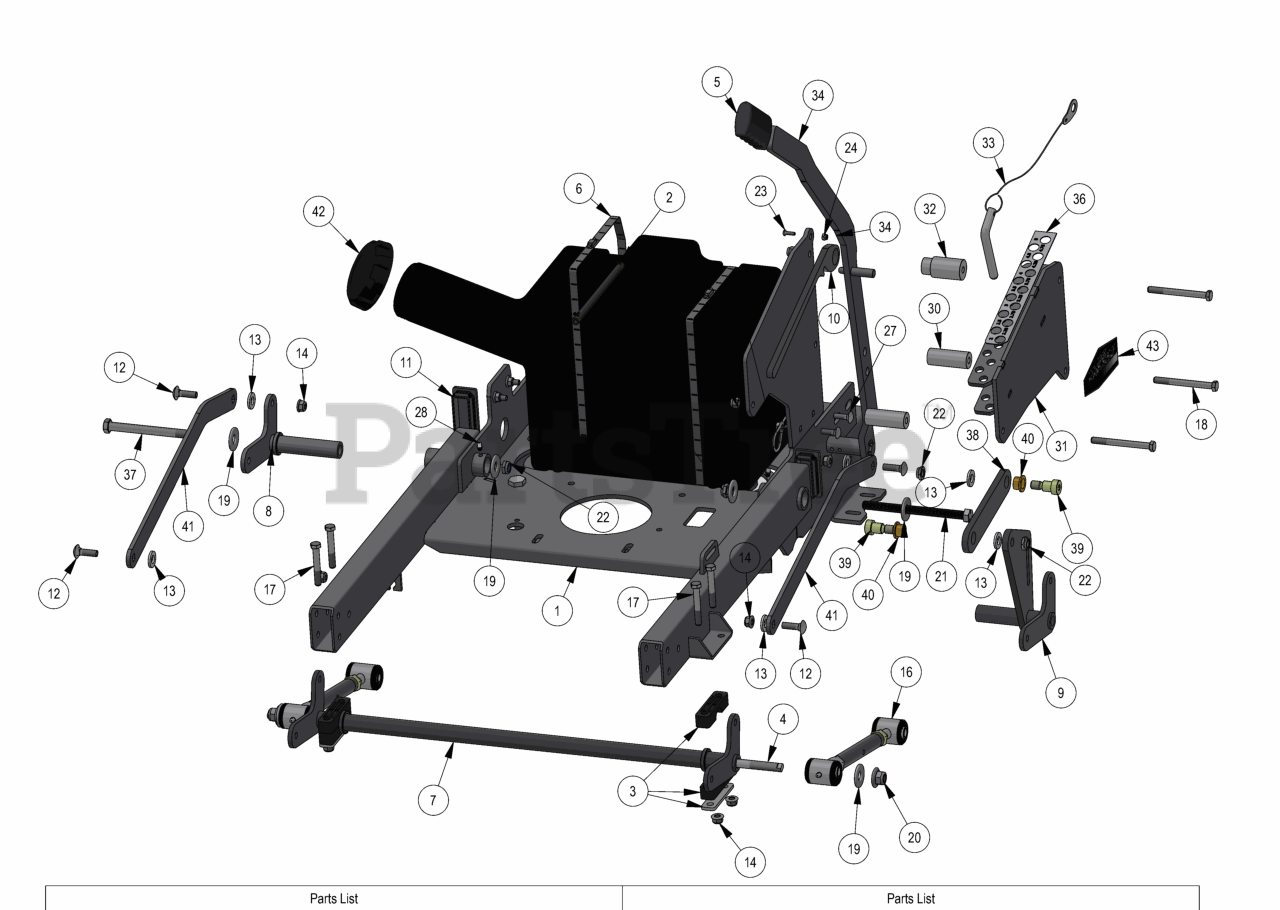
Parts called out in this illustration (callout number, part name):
1	2020 36" Stand On Frame
2	Revolt Fuel Line Assembly
3	Pillow Block Kit
4	2020 36 Stand On Turnbuckle Rod
5	2019 Stand On Lift Grip
6	2019 Stand On Gas Tank Strap
7	Revolt Front Actuator Bar Weldment 2020 36" Black
8	Revolt Rear Actuator Bar Weldment RH 2020 36" Black
9	Revolt Rear Actuator Bar Weldment LH 2020 36" Black
10	2019 Stand On Deck Lever Lock
11	1 1/2 x 3 Frame Plug
12	3/8-16 X 1-1/4 CARRIAGE BOLT ZINC
13	.505 ID X 1.000 OD X .125 THICK FLAT WASHER NYLON
14	3/8" Nylock Flange Nut
15	Revolt Cotter Pin for 7/8" to 1" shank
16	2018 Maverick Turnbuckle (Top Link)
17	3/8-16 X 2-1/2 HEX CAP SCREW (GR.5) ZINC
18	3/8-16 X 3-3/4 HEX CAP SCREW (GR.5) ZINC
19	1/2" Flat Washer
20	1/2-13 NYLON INSERT FLANGE LOCKNUT ZINC
21	1/2-13 x 6 1/2 Hex Bolt
22	1/2''-13 Jam Nut
23	10-24 X 5/8 BUTTON SOCKET CAP SCREW 18-8 STAINLESS STEEL
24	10-24 NYLON INSERT LOCKNUT ZINC
25	3/8 Nylock Nut
26	5/16" Nylock Flange Nut Zinc
27	5/16-18 X 1 CARRIAGE BOLT (GR.8) ZINC
28	1/4" Press in Grease Fitting
29	2023 Stand On Inner Adjustment Plate
30	Stand On Spacer 2.5''
31	2023 Stand On Outer Adjustment Plate weldment
32	Stand On Spacer 2.5'' With shoulder
33	2023 stand on Height Adj Pin
34	2023 Stand On SD Lift Lever Weldment
36	2023 Revolt Deck Hight decal
37	1/2-13 X 5 1/2 HEX CAP SCREW (GR.5) ZINC
38	2023 lever secondary linkage
39	5/8'' x 5/8'' Shoulder Bolt
40	.627 ID X .753 OD X .500 LGTH X 1.000 FLG OD X .094 FLG THICK
41	2023 SD-36 Stand-on Actuator Linkage
43	Revolt Deck Height Decal
